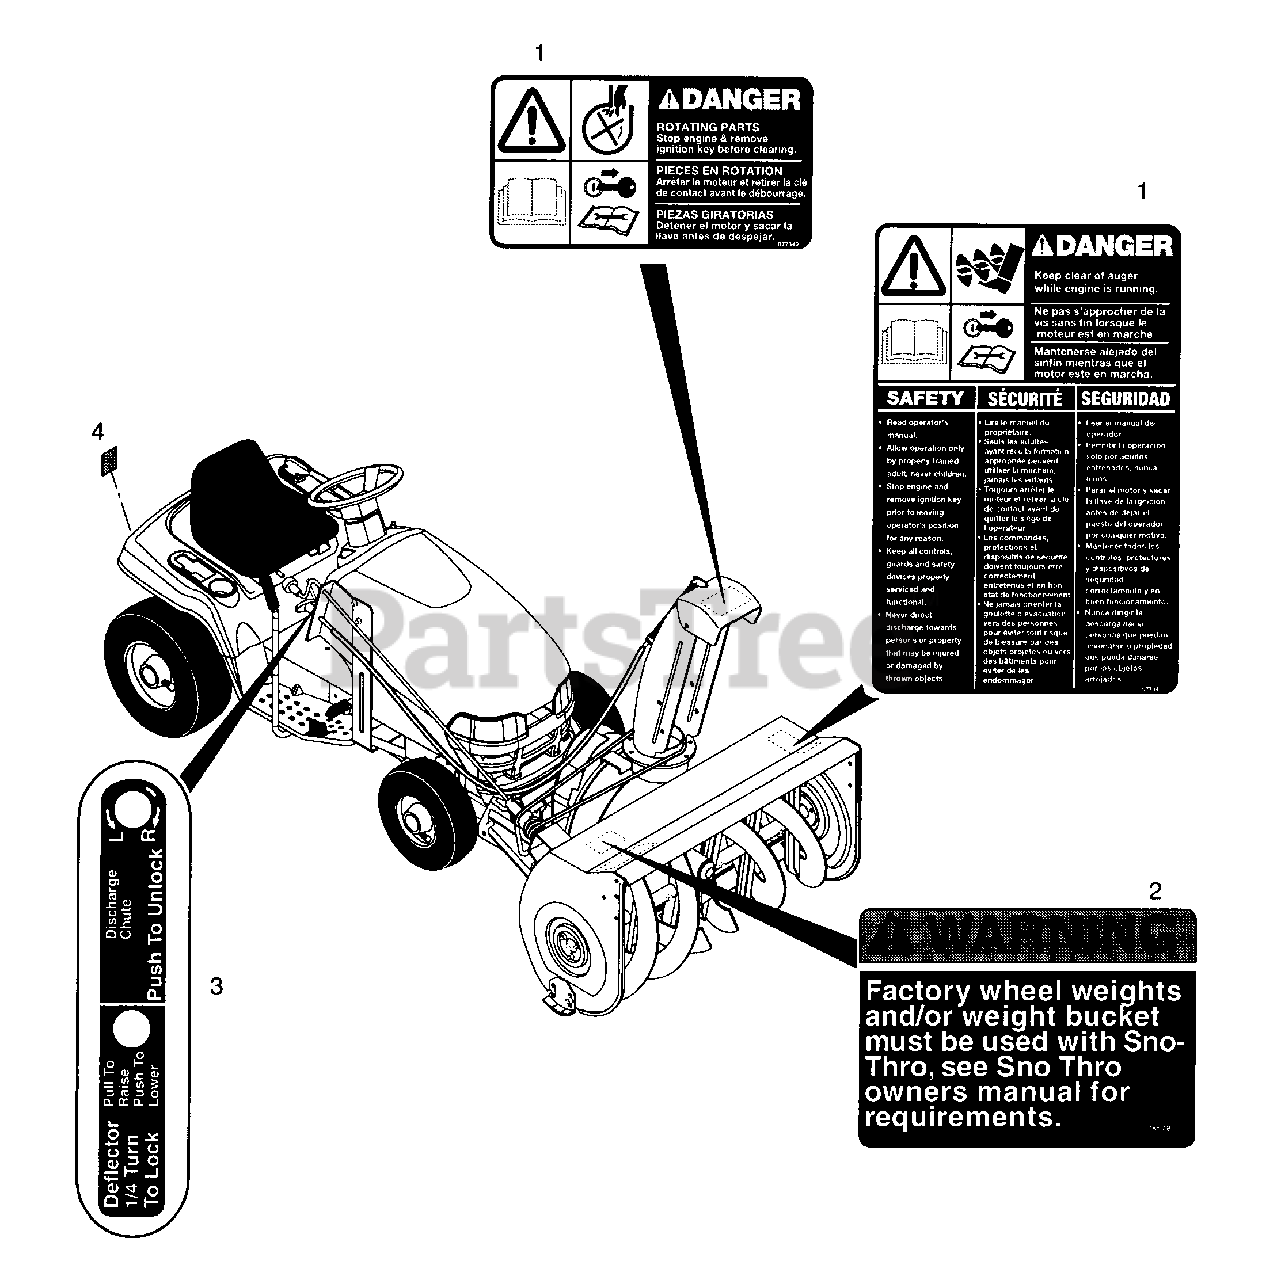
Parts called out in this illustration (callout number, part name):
1	DECAL SET - DANGER
2	WARNING WHEEL WEIGHT DECAL
3	CHUTE CRANK DECAL
4	REFLEX REFLECTOR
